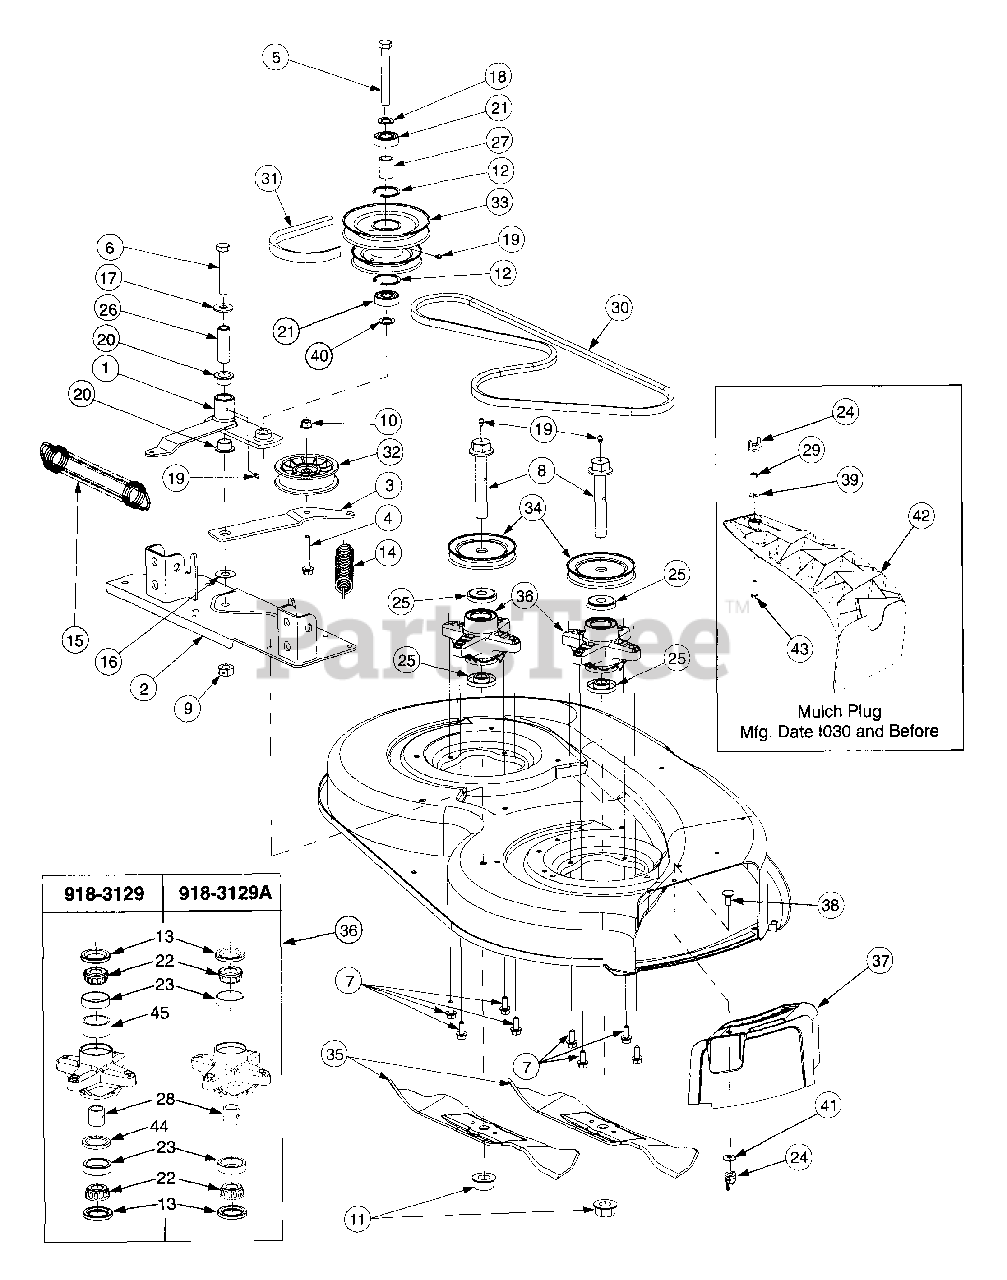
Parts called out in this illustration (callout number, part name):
2	Plate Assembly, Mounting
4	Screw, Hex Cap, 3/8-16 x 1.5 GR5
5	Screw, Hex Cap, 5/8-18 x 3.0 GR5
6	Screw, Hex Cap, 1/2-20 x 3.0 GR8
7	Screw, Hx Wsh Hd Tapp, 5/16-18 x .75
8	Bolt, Spindle, 3/4-16 x 4.25
9	Nut, Hex Center Lock, 1/2-20
10	Nut, Hex Flange Lock, 3/8-16
11	Nut, Hex Flange, 3/4-16
12	Snap Ring, Internal
13	Seal, Oil, 1.25 x 1.874 x .25
14	Spring, Extension, .88 x 6.12
15	Spring, Extension, 1.25 x 8.15
16	Washer, Flat, .531 x 1.25 x .036
17	Washer, Flat, .531 x 1.25 x .100
18	Washer, Flat,
19	Fitting, 3/16 Drive Lube
20	Bearing, Flange, 3/4 ID x .53 Lg
21	Bearing, Ball, .62 ID x 1.57 OD
22	Cone, Bearing
23	Cup, Bearing
24	Nut, Wing, 1/4-20
25	Spacer, Deck Spindle
26	Spacer, Idlr Brkt .50 ID x .75 OD x 2.25
27	Spacer, Pulley, .635 ID x .88 OD x 1.25
28	Spacer, Bearing, .780 x .963 x .7777
29	Nut, Hex, 1/4-20
30	Belt, Spindle, A-Section x 59 Lg
31	Belt, PTO, B-Section x 112.4 Lg
32	Pulley, Flat Idler, 3.5 OD
33	Pulley, Double
34	V-Pulley, 4.0 Dia
35	Blade, 3 In One, 19.38 Lg
36	Spindle Assy
37	Plug, Mulch
38	Screw, Carriage, 1/4-20 x .62
39	Washer, Flat, .28 x .74 x .063
40	Washer, Flat, .65 x 1.25 x .075 Hdn
41	Washer, Belleville, .265 x .75 x .062
42	Plug, Mulch
43	Screw, Hex Cap, 1/4-20 x 1.0 GR5
44	Spacer, Bearing
45	Spacer, Bearing, 1.5 x 1.7525 x .8275
